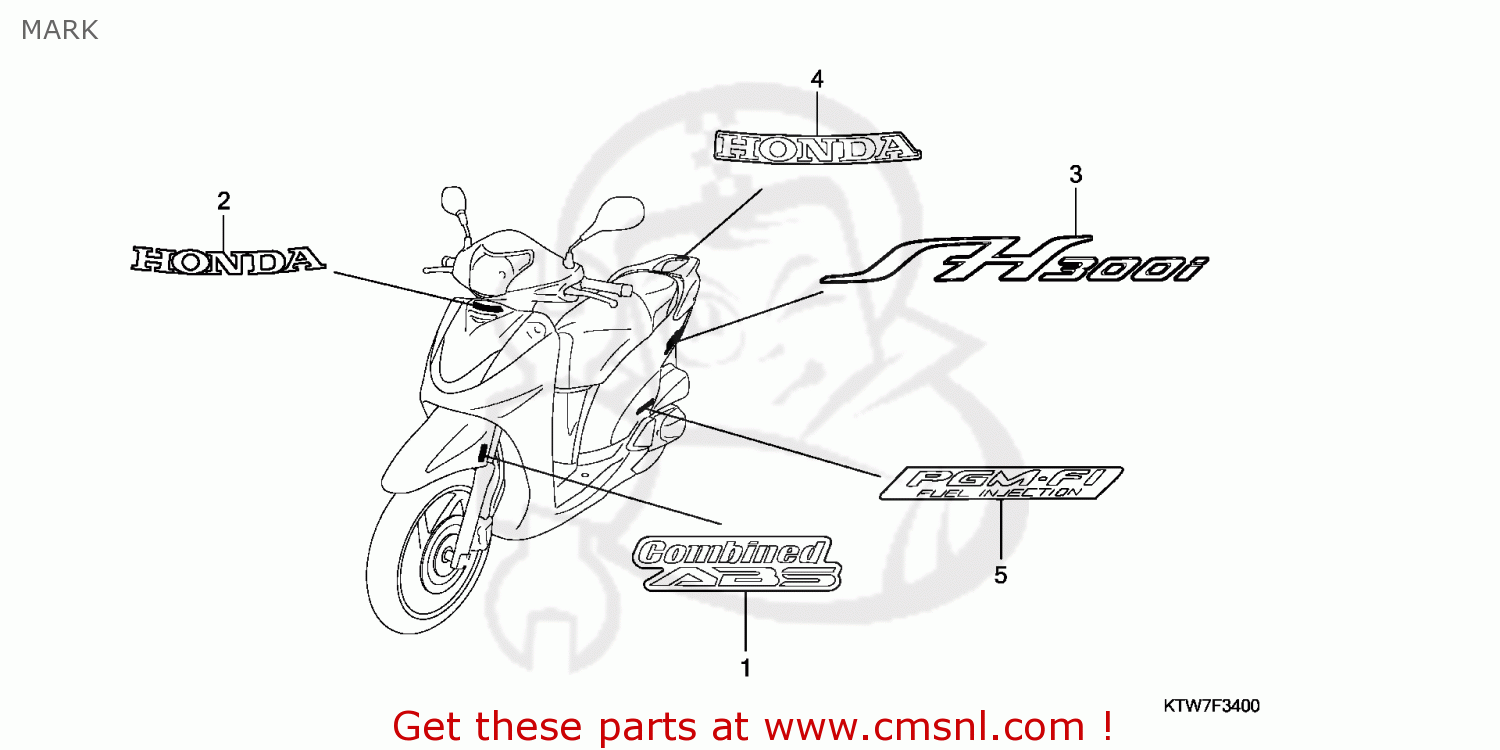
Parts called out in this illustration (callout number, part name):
1	MARK,COMBI*TYPE1*
2	EMBLEM,HONDA
3	MARK,BODY *TYPE1*
4	MARK,HONDA*TYPE1*
5	MARK,PGM *TYPE1*
